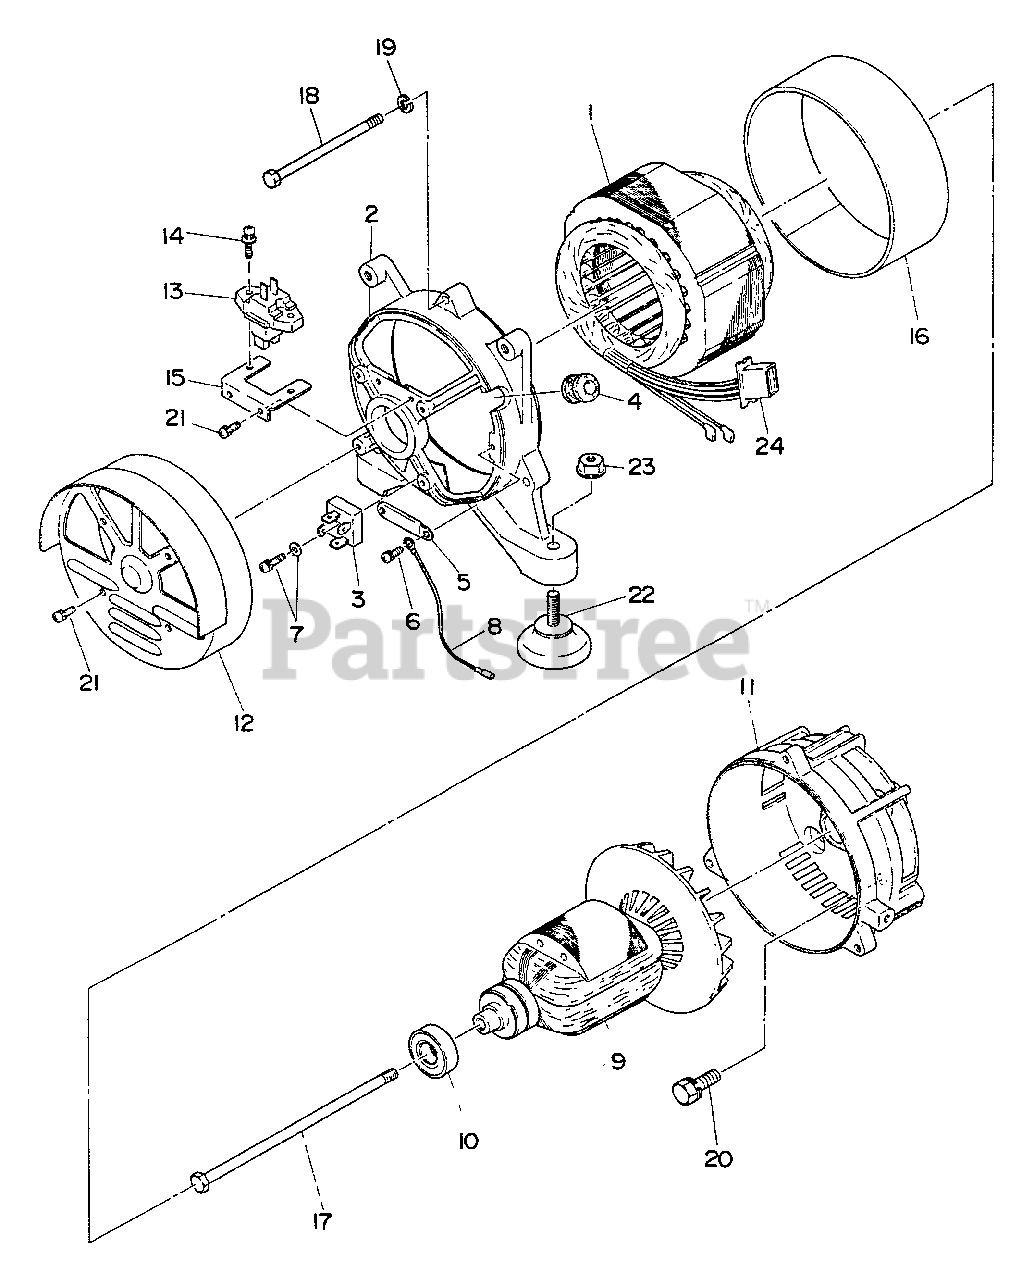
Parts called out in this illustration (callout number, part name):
1	STATOR ASSY
2	BRACKET, REAR
3	DIODE STACK ASS'Y
4	GROMMET
5	CLAMP
6	SCREW
7	SCREW
8	EARTH WIRE, COMPL
9	ROTOR ASSY
10	BEARING, BALL
11	BRACKET, FRONT
12	END COVER
13	HOLDER, BRUSH
14	SCREW
15	BRUSH HOLDER BASE
16	STATOR COVER
17	THROUGH BOLT
18	BOLT
19	LOCKWASHER
20	BOLT
21	SCREW
22	MOUNT ASSY
23	NUT, FLANGE
24	LABEL - GENERATOR
